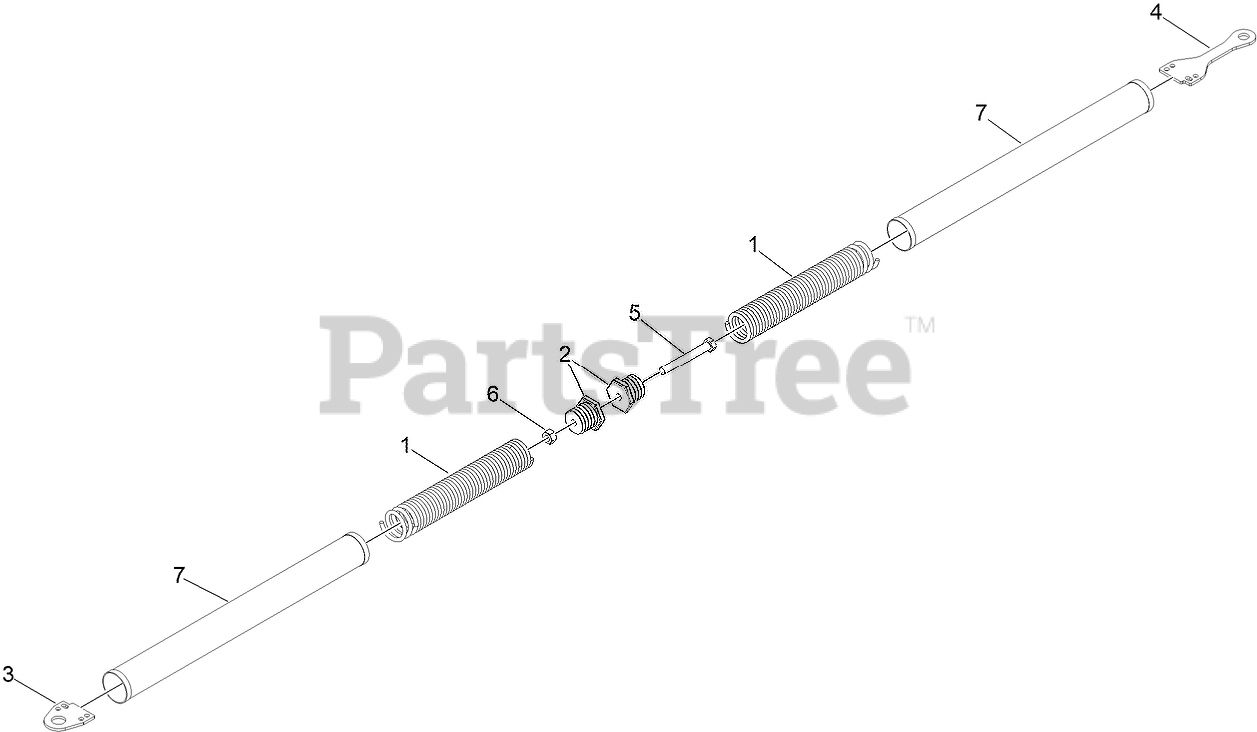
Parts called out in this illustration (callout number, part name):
1	SPRING-EXTENSION
2	PLUG-ADJUSTER, SPRING
3	PLATE-SPRING EYE
4	SPRING-TAB
5	BOLT-TAP
6	NUT-HH
7	COVER-SPRING, DECK
